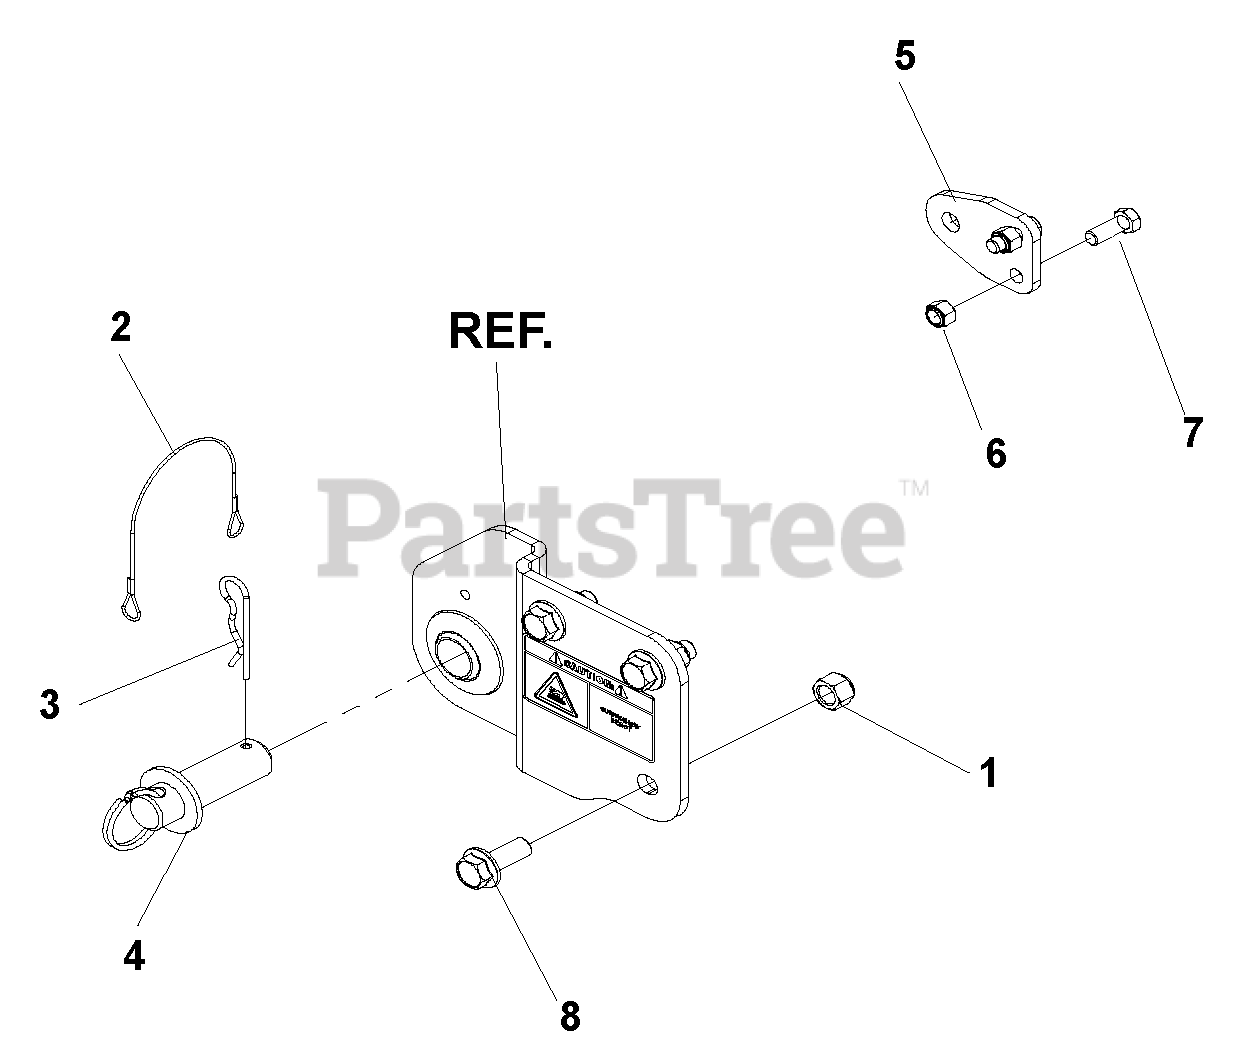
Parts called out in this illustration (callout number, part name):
1	NUT, 1/2-13, NYLOC
5	SUPPORT BRACKET
6	NUT, 3/8-16, NYLOC
7	HCS, 3/8-16 X 1, GR5
8	BOLT, 1/2-13 X 1 1/4, WHIZLK
